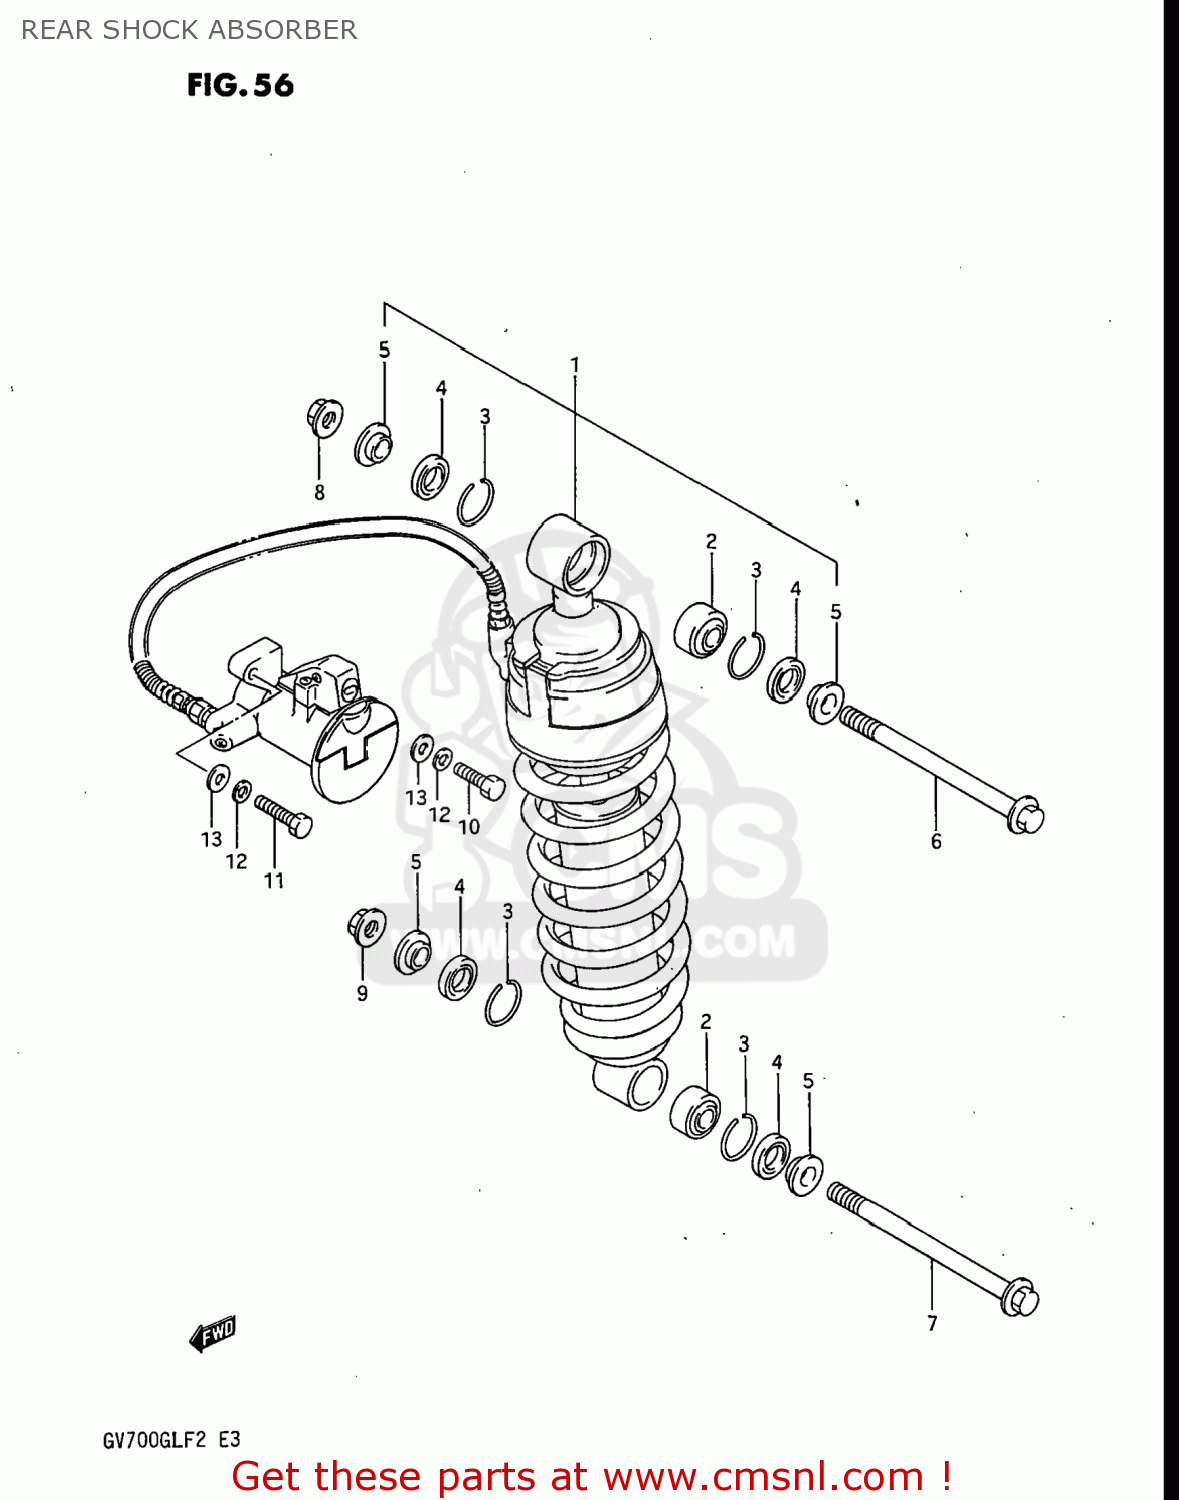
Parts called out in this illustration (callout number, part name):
1	ABSORBER ASSEMBLY,REAR SHOCK
2	BEARING,REAR SHOCK ABSORBER
3	RING
4	SEAL,DUST
5	SPACER
6	BOLT,REAR SHOCK ABSORBER
7	BOLT(10X118)
8	NUT
9	NUT 10MM
10	BOLT
11	BOLT
12	LOCK WASHER
13	WASHER
